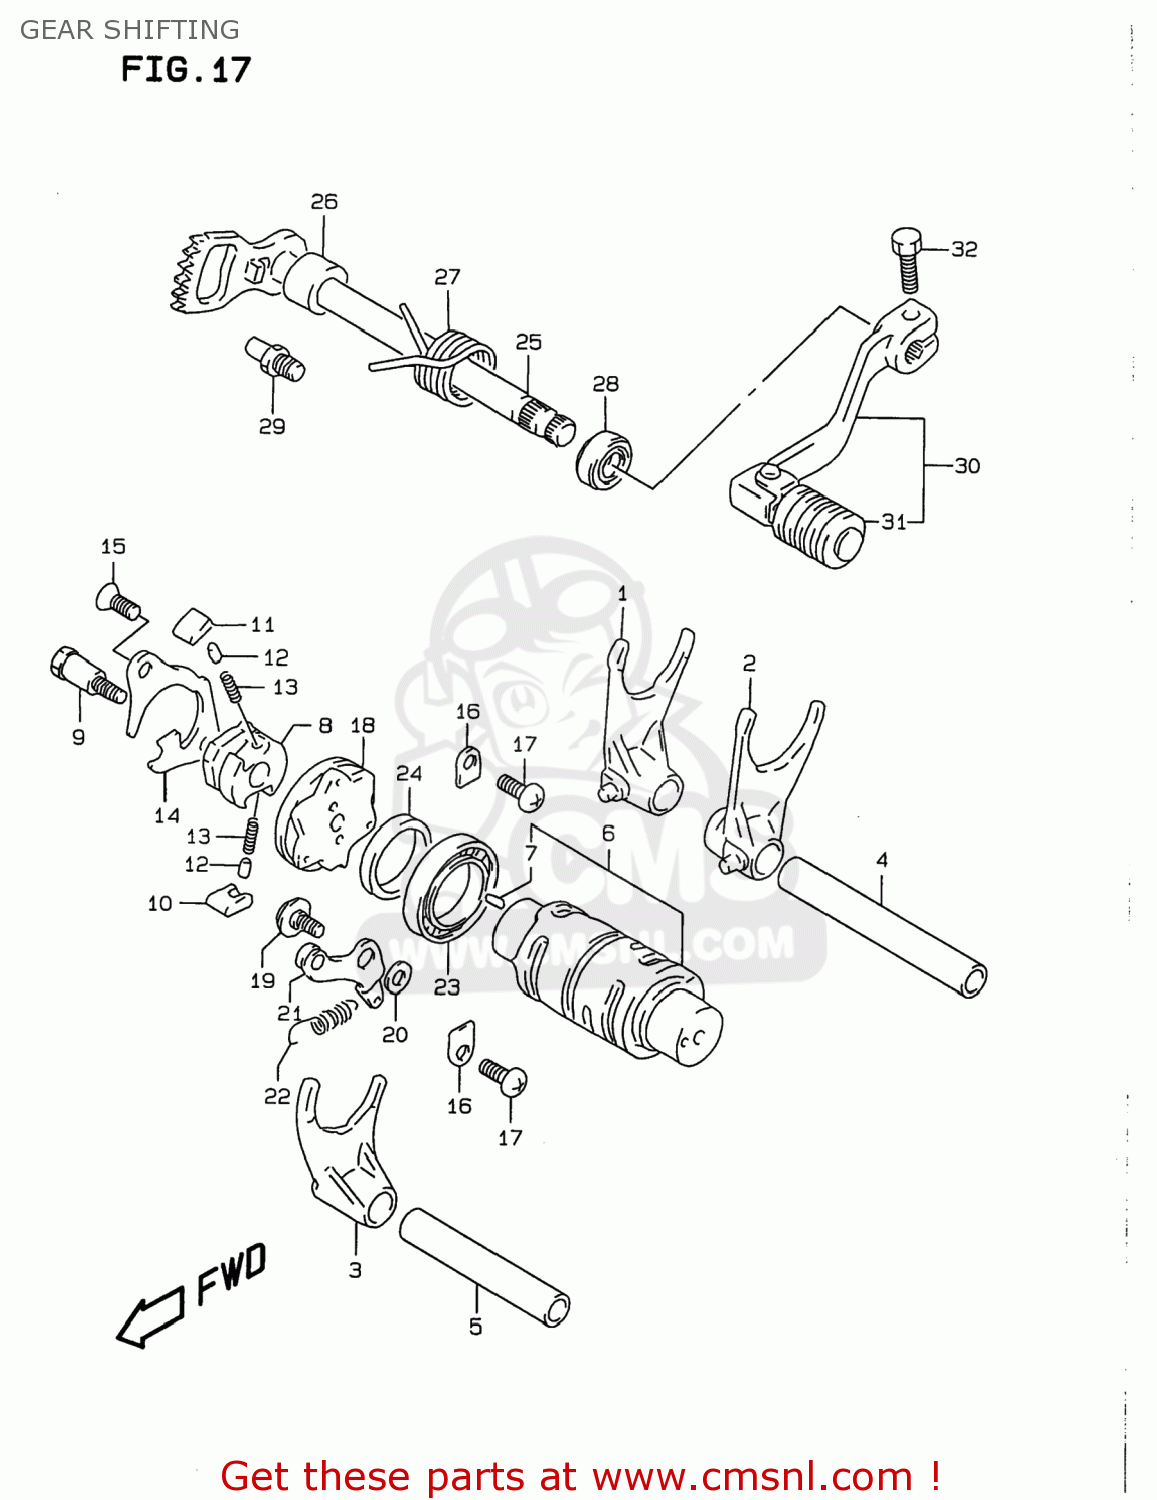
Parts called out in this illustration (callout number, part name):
1	FORK,GEAR SHIFT NO.1
2	FORK,GEAR SHIFT NO.2
3	FORK,GEAR SHIFT NO.3
4	SHAFT,GEAR SHIFT FORK
5	SHAFT,GEAR SHIFT FORK(L:70)
6	CAM,GEAR SHIFT
7	PIN
8	GEAR,GEARSHIFT CAM DRIVE
9	PIN,SHIFT CAM DRIVEN GEAR
10	PAWL,GEAR SHIFT NO.1
11	PAWL,GEAR SHIFT NO.2
12	PIN(5X8)
13	SPRING
14	LIFTER,GEAR SHIFT PAWL
15	SCREW
16	RETAINER
17	SCREW
18	PLATE,GEAR SHIFT CAM
19	BOLT(6X14.3)
20	WASHER
21	STOPPER,GEAR SHIFT CAM
22	SPRING
23	BEARING
24	WASHER(25X32X5.3)
25	SHAFT,GEAR SHIFT
26	SPACER(12X20X15.3)
27	SPRING
28	OIL SEAL
29	STOPPER,GEAR SHIFT ARM
30	LEVER ASSY,GEAR SHIFT
31	RUBBER,GEAR SHIFT PEDAL
32	BOLT
